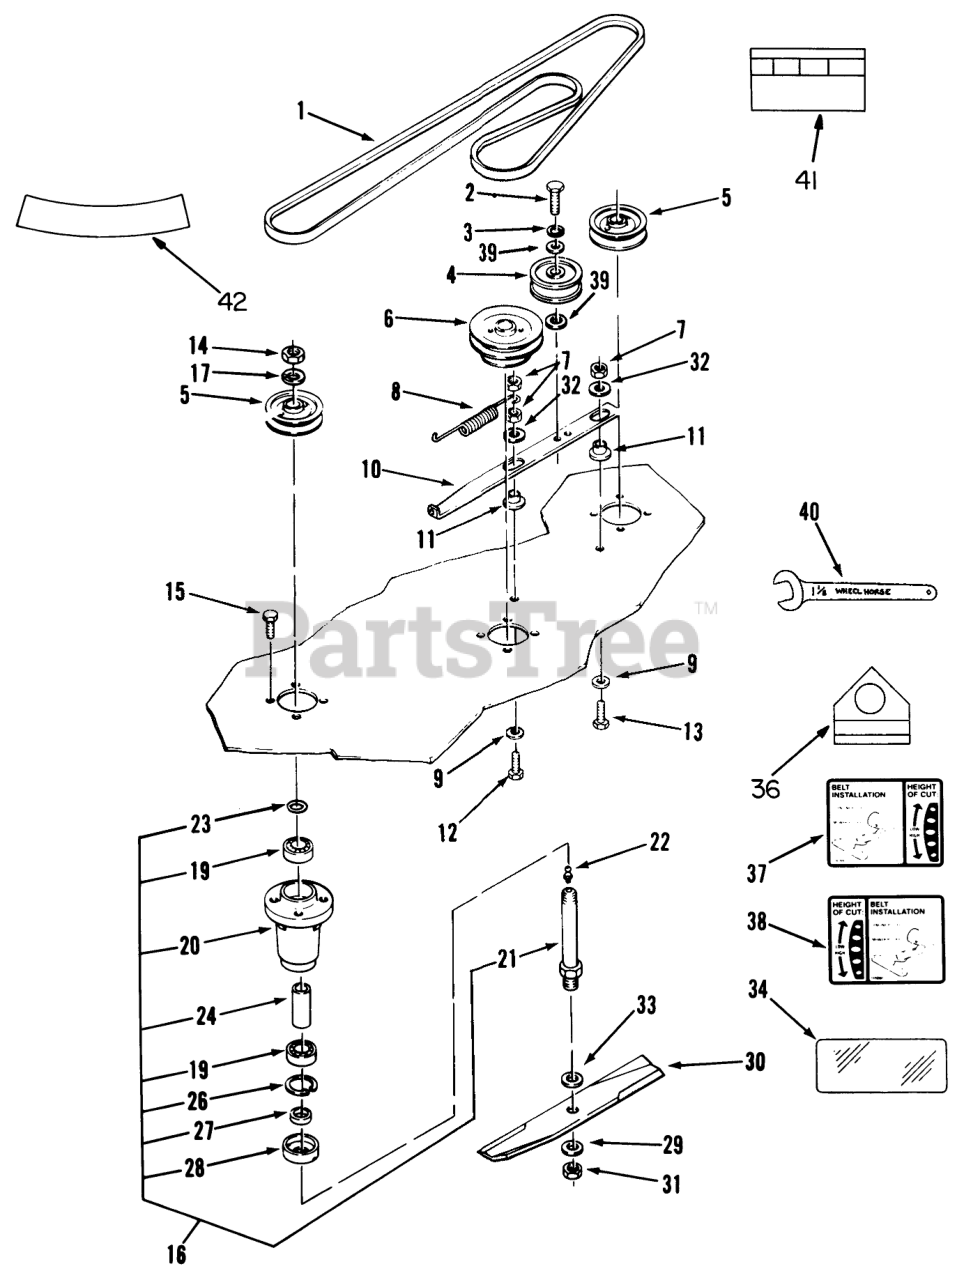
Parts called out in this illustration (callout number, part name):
1	V-BELT
1	V BELT
2	Bolt
3	LOCKWASHER
4	Pulley
4	Idler Pulley
5	PULLEY-BLADE, DRIVE
5	PULLEY
6	PULLEY-MOWER, 48IN
6	PULLEY
7	NUT
8	SPRING-EXTENSION
9	WASHER
10	BAR-IDLER SUPPORT
11	SPACER-BUSHING
12	Bolt
13	Bolt
14	Nut
15	Bolt
16	Spindle Assembly (Incl. Ref. #19-24, & 26-28)
17	Lockwasher
19	BEARING-BALL
20	HOUSING-SPINDLE
21	SHAFT-SPINDLE
22	Zerk
23	O RING
26	Ring-Snap
27	SPACER-BLADE
28	CUP-SPINDLE
29	Washer
30	Blade
30	BLADE-14IN
31	Nut-Jam
32	WASHER
33	Washer
34	DECAL-OVERLAY
36	DECAL-DANGER
37	DECAL-HEIGHT & BELT
38	DECAL-HEIGHT & BELT
39	Washer
40	Spindle Wrench
41	DECAL-DANGER, THROWN OBJECT
42	DECAL - DANGER
